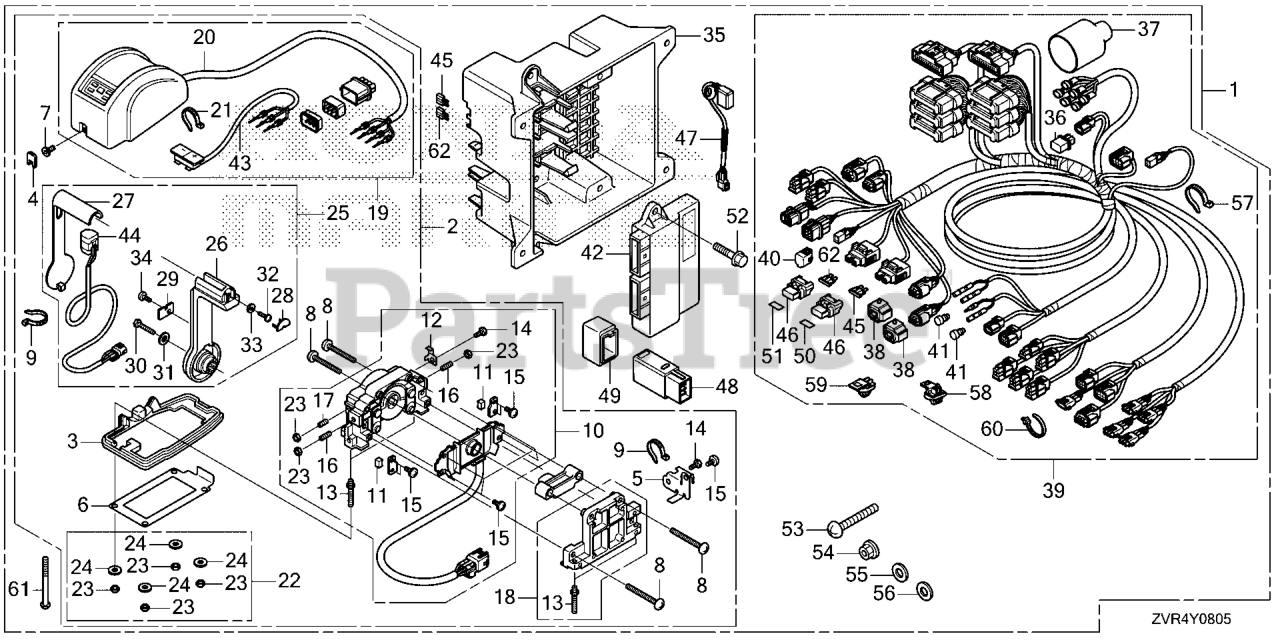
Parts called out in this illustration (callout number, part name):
1	BOX KIT, R/C
2	BOX ASSY., REMOTE CONTROL (TOP MOUNT SINGLE)(RH)
3	GASKET (SINGLE)
4	COVER, CAP
5	PLATE, COVER FIX (SINGLE)
6	SHEET, WATERPROOF (SINGLE)
7	BOLT, SOCKET
8	SCREW
9	BAND, NYLON
10	HOUSING ASSY., L.
11	SHOE, BRAKE
12	PLATE, HARNESS
13	BOLT, STUD
14	BOLT
15	SCREW
16	SCREW SET
17	SCREW SET
18	HOUSING ASSY., SINGLE
19	COVER ASSY., SINGLE
20	LED ASSY., COVER (S)
21	BAND, NYLON
22	NUT SET, MOUNTING
23	NUT
24	WASHER
25	LEVER ASSY., L.
26	LEVER
27	PANEL, LEVER (POWER TRIM-TILT)
28	CAP, LEVER
29	PLATE, LEVER PANEL
30	BOLT
31	WASHER
32	SCREW
33	WASHER
34	SCREW
35	CASE, CONTROL UNIT
36	TERMINATOR ASSY.
37	COVER, CONNECTOR (NOT AVAILABLE)
38	SUSPENSION, CONNECTOR
39	CABLE, REMOTE CONTL
40	CAP, DUMMY (WPC 4P 090 M) (RED)
41	PLUG, CONNECTOR (INNER) (TROLLING CONTROL)
42	UNIT ASSY., CONTL
43	SWITCH ASSY., SELECT
44	SWITCH ASSY., POWER TRIM-TILT
45	FUSE, BLADE (3A)
46	COVER ASSY., FUSE
47	RELAY ASSY., CONTROL (NOT AVAILABLE)
48	RELAY ASSY., MAIN
49	SUSPENSION, RELAY
50	LABEL, FUSE (3A)
51	LABEL, FUSE (5A)
52	BOLT, FLANGE (6X20)
53	SCREW, PAN (5X40) DUAL QTY = (8) (SINGLE)
54	NUT, FLANGE (5MM)
55	WASHER, PLAIN (5MM)
56	WASHER, SPG (5MM)
57	HOLDER, CONNECTOR (128.6MM) (NATURAL)
58	CLIP, CONNECTOR (DARK BLUE)
59	CLIP, CONNECTOR (DARK BROWN)
60	CLIP, HARNESS BAND (145MM) (BLACK)
61	SCREW, PAN (5X65)
62	FUSE, MINI (5A)
